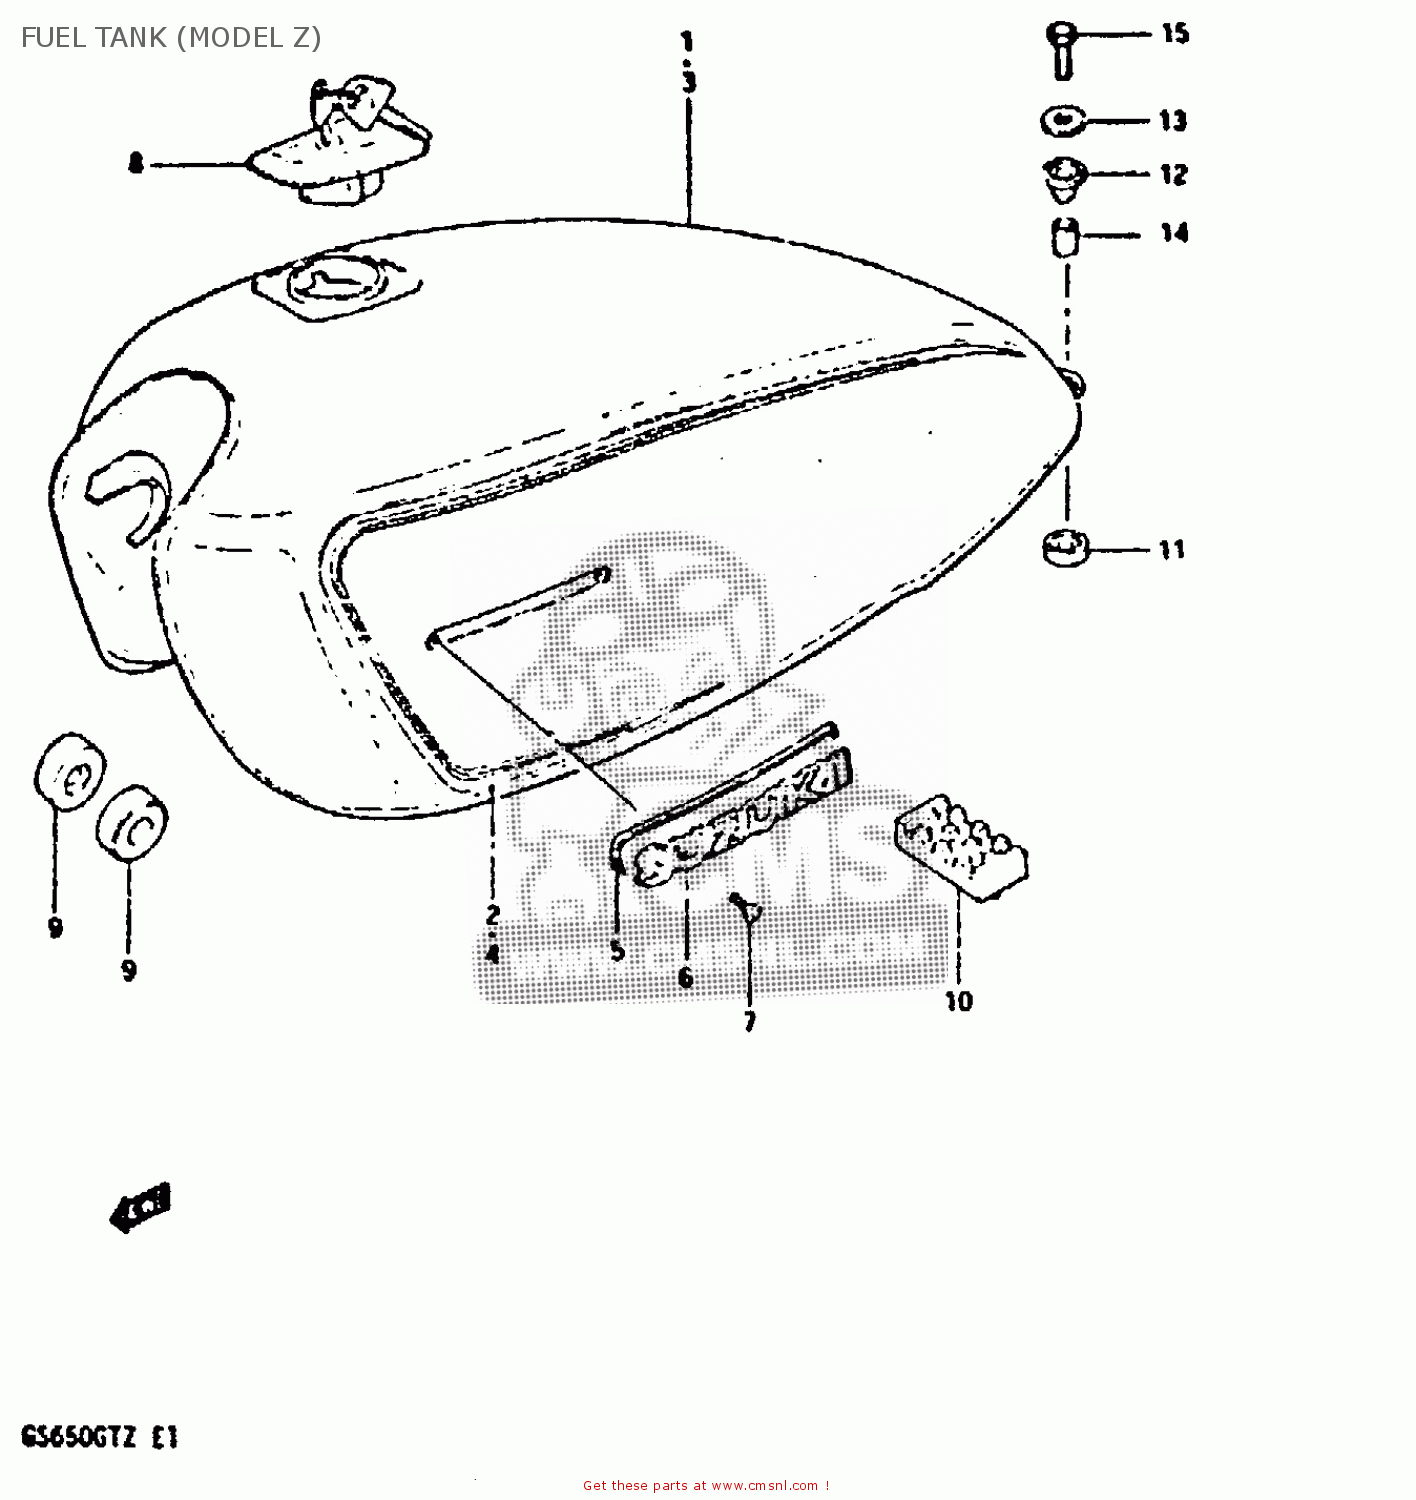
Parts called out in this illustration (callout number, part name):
1	TANK ASSEMBLY,FUEL
2	TAPE SET,FUEL TANK
3	TANK, FUEL (MAROON)
4	TAPE SET,FUEL TANK
6	EMBLEM,FUEL TANK
7	SCREW 3X6
8	CAP SET,FUEL TANK
9	CUSHION
10	CUSHION,FUEL TANK CTR
11	CUSHION
12	CUSHION
13	WASHER (6.5X24X1.6)
14	SPACER
15	BOLT
